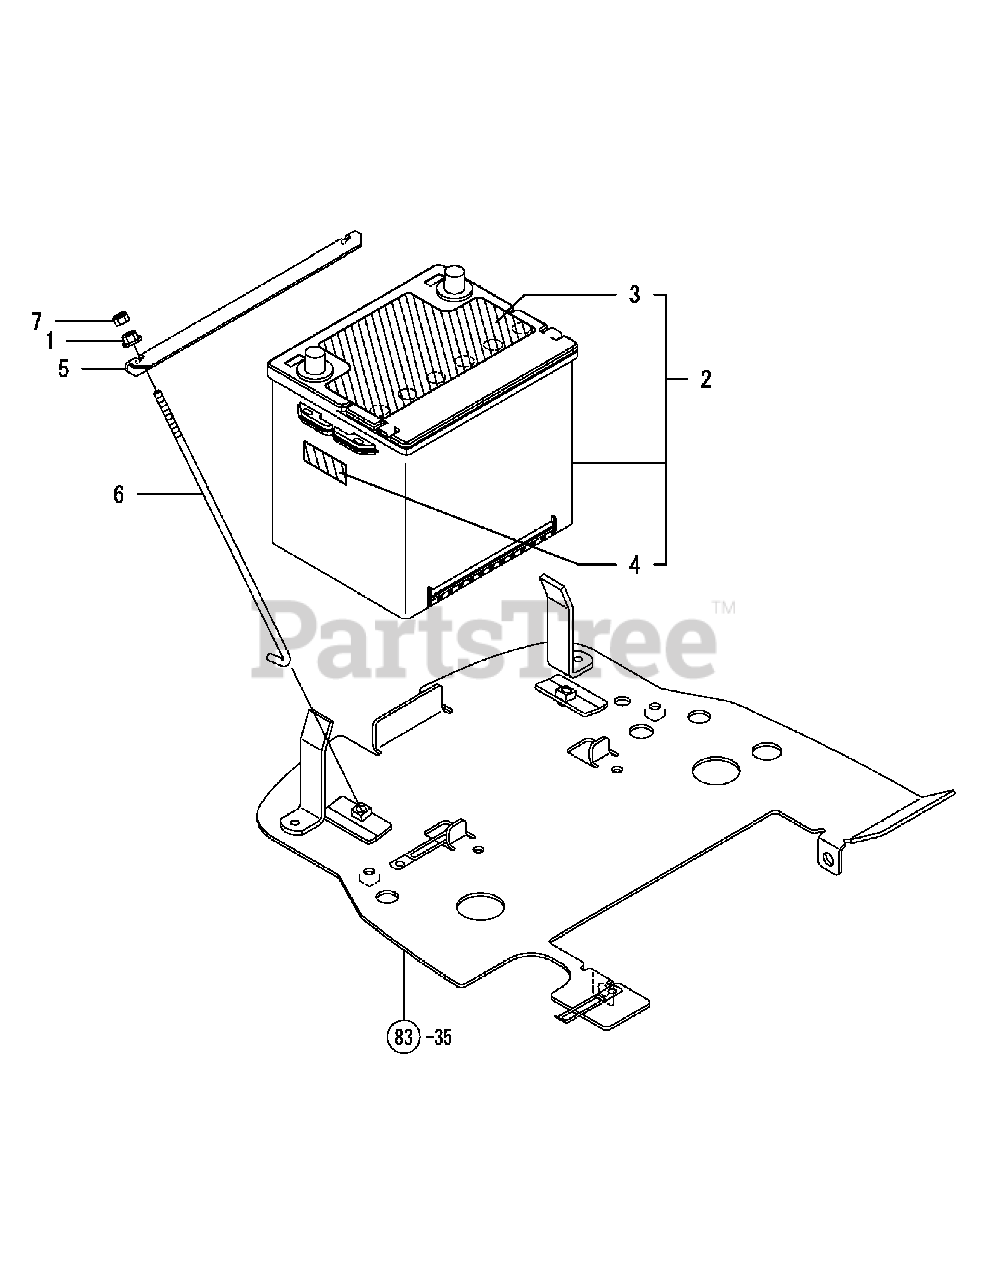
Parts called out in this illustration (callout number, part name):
1	Nut W/Washer 6
2	Battery, 26R, Assy
3	Label, Battery
4	Label, Ca, 65, Warn
5	Clamp, Battery,6-245
